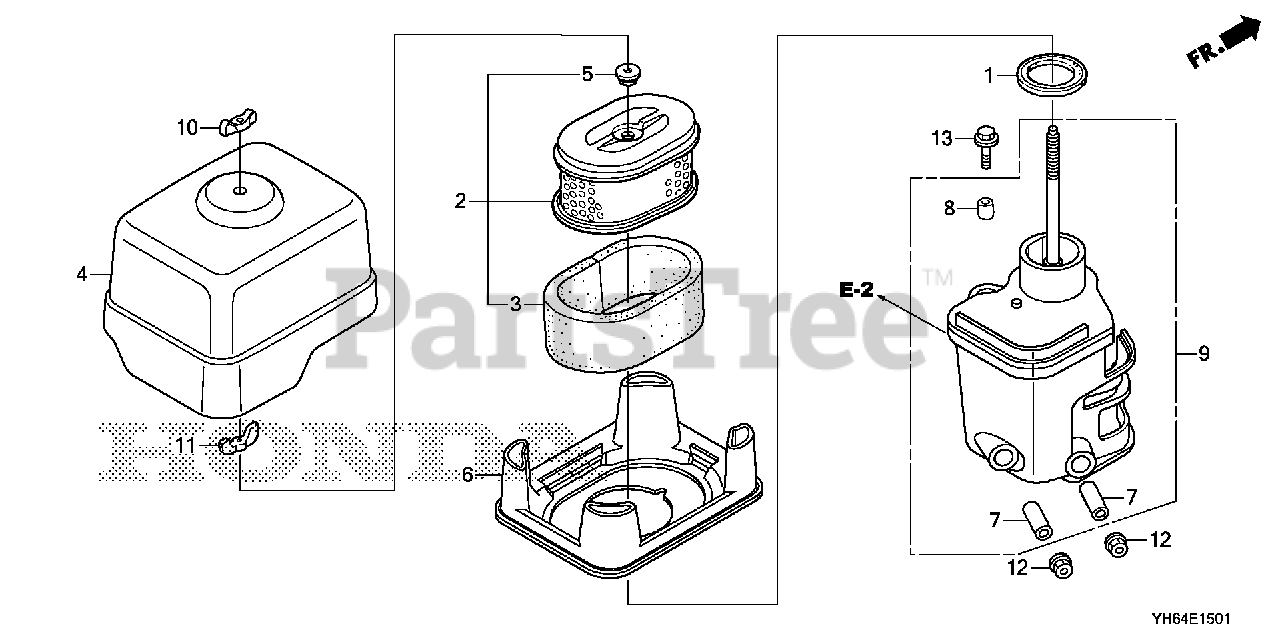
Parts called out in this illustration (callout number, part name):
1	GASKET, ELBOW
2	ELEMENT, AIR CLEANER (DUAL)
3	FILTER (OUTER)
4	COVER, AIR CLEANER
5	GROMMET, AIR CLEANER
6	NOSE, MUFFLER
7	COLLAR, AIR CLEANER Use from Engine SN 1786085.
8	COLLAR B, AIR CLEANER
9	ELBOW, AIR CLEANER
10	NUT, AIR CLEANER
11	WINGNUT, TOOL BOX SETTING
12	NUT, FLANGE (6MM)
13	BOLT, FLANGE (6X20)
